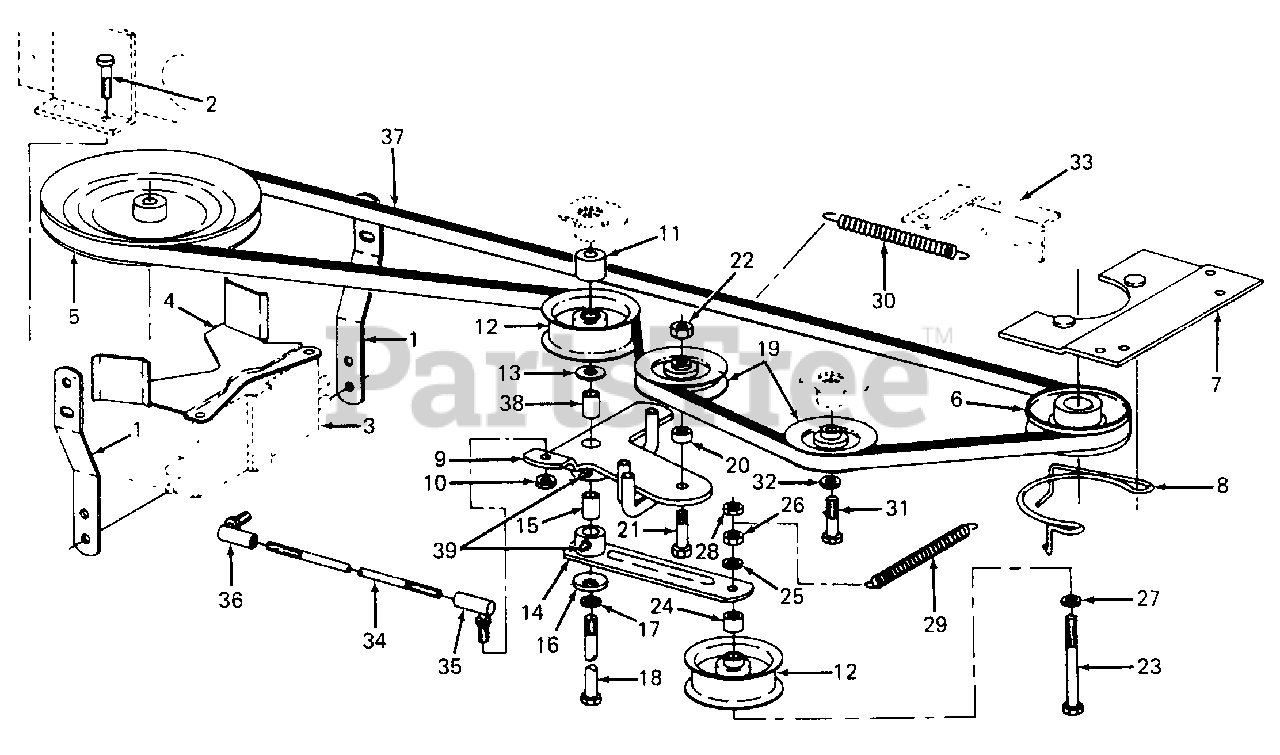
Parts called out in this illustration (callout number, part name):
1	Brace, Transmission
2	Bolt, 5/16 X 2-1/2 GR 5
3	Transaxle -5 Speed For Components SeeTransaxle
4	Support, Belt Keeper
5	Pulley, Transmission
6	Pulley, Engine (3.5 OD)
7	Plate, Belt Guide Mounting
8	Guide, Belt
9	Bracket Assy, Clutch
10	Nut, 5/16 Hex
11	Bushing, .390 X 1.0 X .812
12	Pulley, Flat Idler (2.75 OD)
13	Washer, .385 X .87 X .06 Hdn
15	Spacer, .377 X .06 X .83
16	Washer, .400 X 1.25 X .157 Belleville
17	Washer, 3/8 Lock
18	Bolt, 3/8 X 4-3/4 GR 5
19	Pulley, (3.06 OD)
20	Spacer, .380 X .625 X .270
21	Bolt, 3/8 X 1-3/4 GR 5
22	Nut, 3/8 Cad P/T Lock GR 5
23	Bolt, 3/8 X 2-3/4 GR 5
24	Spacer, .375 X .625 X .445
25	Washer, 3/8 Lock
26	Nut, 3/8 Jam GR 5
27	Washer, .385 X .62 X .063
28	Nut, 3/8 Cad P/T Lock GR 5
29	Spring, .41 OD X 6.0 Long
30	Spring, .62 OD X 6.12 Long
31	Bolt, 3/8 X 1-1/4 GR 5
32	Washer, 3/8 Lock
33	Bracket, Spring
34	Rod, Clutch
35	Joint, 5/16 Pln Type G Ball
36	Joint, 5/16 C-Z Type G Ball (LH Thd)
37	Belt, Drive (91.0 Long)
38	Spacer, .380 X .625 X 1.140
39	Fitting, Lube 3/16 Drive
